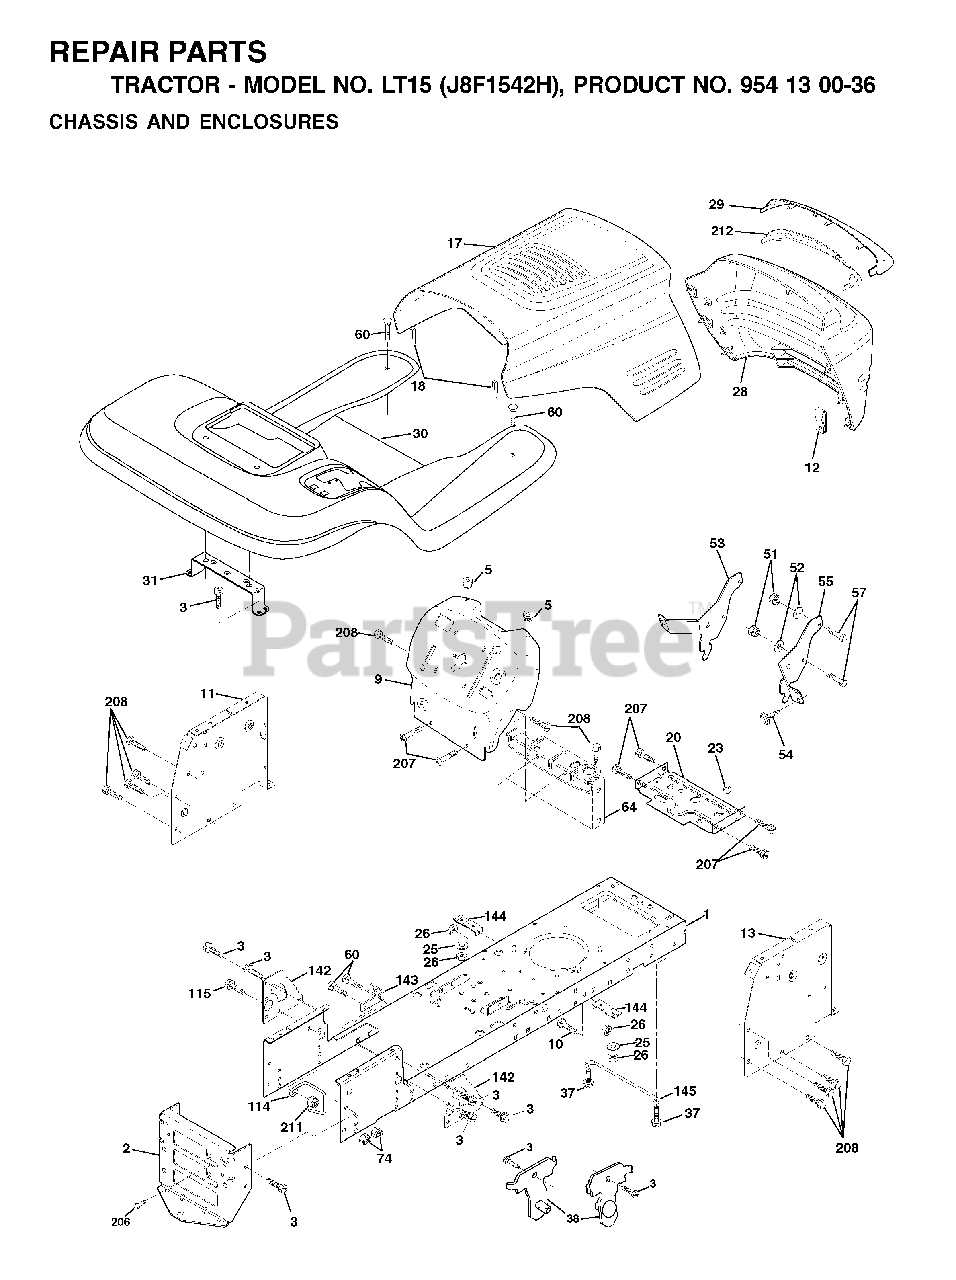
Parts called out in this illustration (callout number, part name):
2	DRAWBAR
3	SCREW 3/8-16X3/4
5	BUMPER.RUBBER.HOOD
10	BOLT D
11	PANEL DASH LH
13	DASH PANEL RH
18	BUMPER HOOD T
20	PLATE MTG
23	GROMMET T
25	WASHER
26	NUT
38	BRACKET
51	LOCKNUT
57	BOLT
64	DASH LOWER
74	LOCKNUT
115	SCREW.3/8-16
142	PLATE
143	BRACKET, SWAY BAR
144	BRACKET FOOTREST
145	ROD PIVOT CHASSIS/HOOD
206	SHOULDER BOLT 5/16-18TT
207	SCREW, 5/16-18 X 1/2
208	SCREW 3/8-16X1/2
211	NUT
